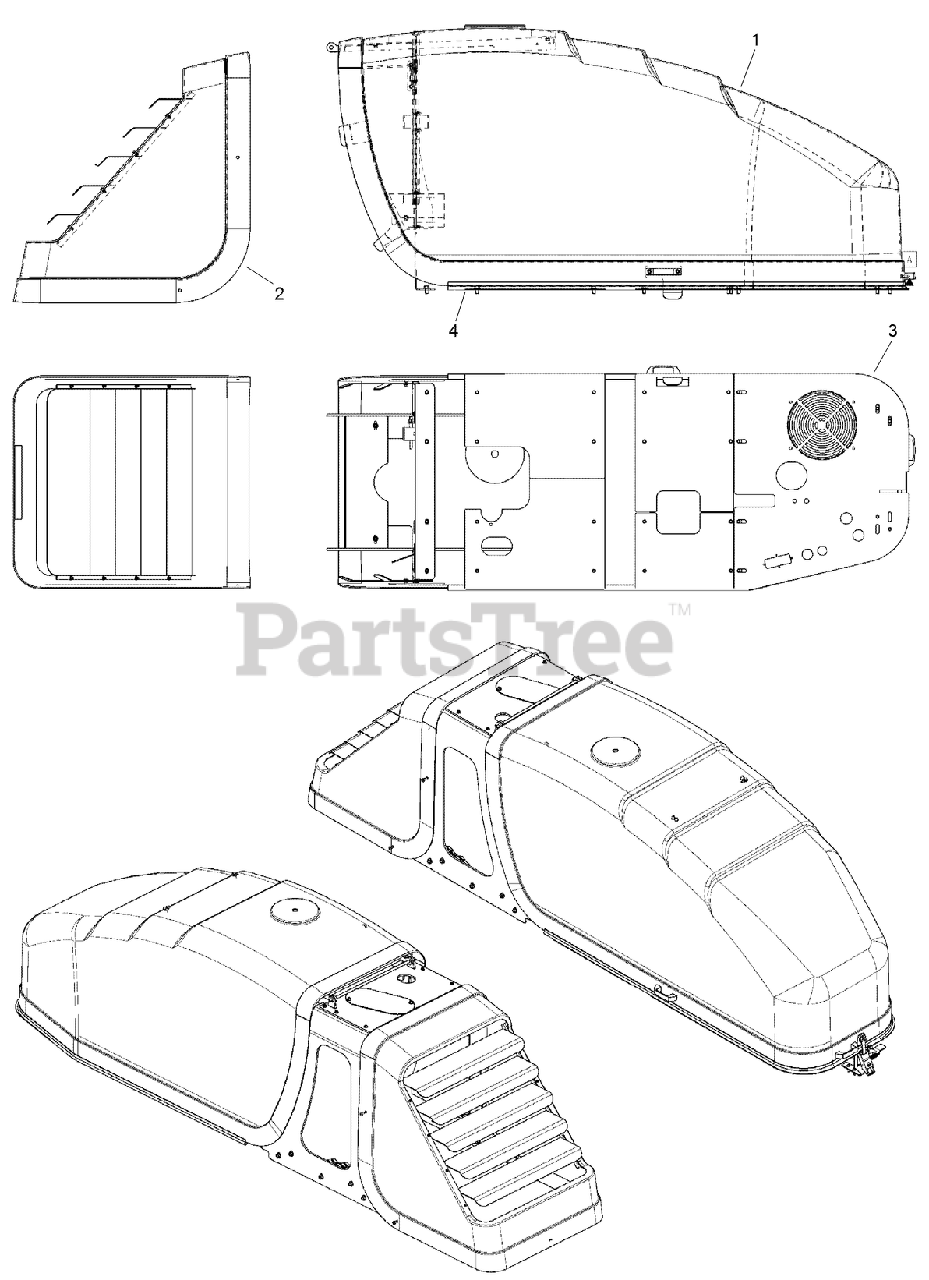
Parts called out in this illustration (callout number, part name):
1	FRONT HOOD ASM
2	REAR HOOD ASM
3	WELDMENT - Seal Plates
4	BULB SEAL - 3805 mm Cut Length
